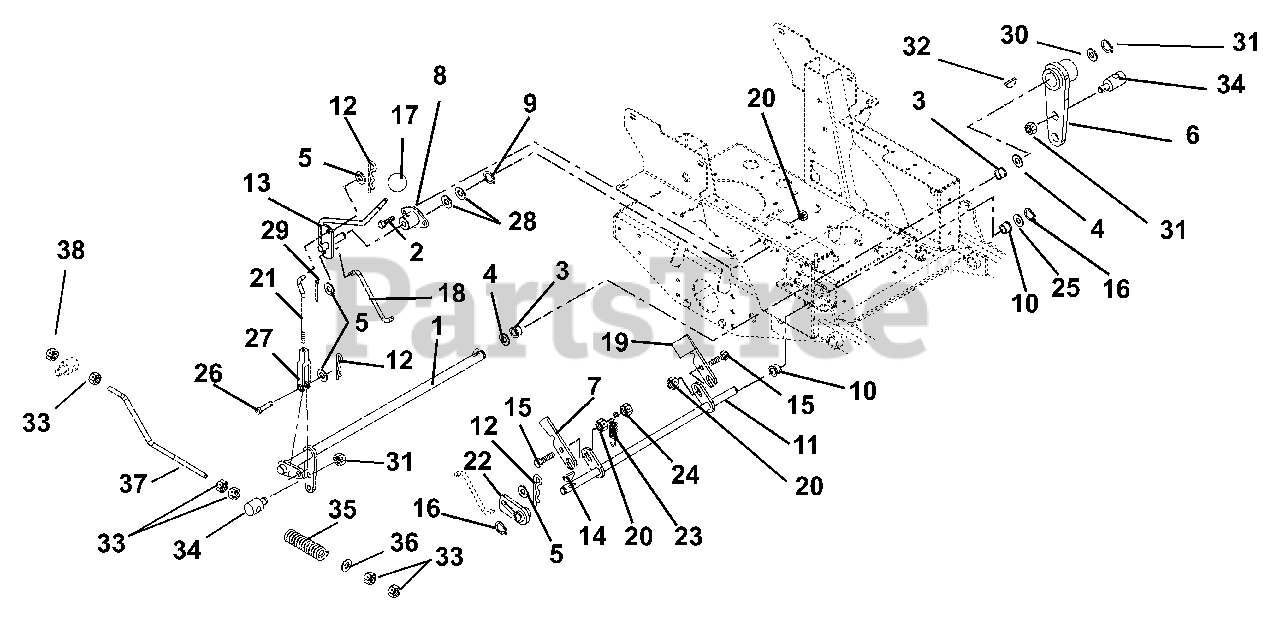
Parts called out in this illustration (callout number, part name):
1	WMT, BRAKE PIVOT
2	@BLT-HEX .31-18X1.00 GR5 YWZC
3	BSHG-FLG .762X1.0X.580X1.48 NY
4	@WSHR-FL-STL.812X1.50X.135YWZC
5	@WSHR-FL-STL.406X.812X.065 YWZ
6	WMT, BRAKE ARM
7	SLIDE, INTERLOCKING BRAKE
8	BUSHING, FLANGED
9	RG-RTNG-EXT .625X.050
10	BSHG-FLG.500X.750X.750X1.000BR
11	WMT, MECHANICAL BRAKE
12	PIN-HAIR, ENDRIES #25 YWZC
13	WMT, BRAKE ACTUATING
14	KEY-WDRF .13X.63 HRD#5
15	@BLT-RDHDSQNK .31-18X1.25 G5YZ
16	RG-RTNG-EXT .500X.050 (SNAP)
17	KNOB-STEERING LOCK
18	LINKAGE, BRAKE ACTUATING
19	INTERLOCK, SAFETY SWITCH
20	@NUT-LK-NYL-FLG .31-18 YWZC
21	LINKAGE, BRAKE COMPACT-Z
22	WMT, PARKING BRAKE HUB
23	SG-TENS .061 X .50 X 3.0 WLD 4
24	@NUT-LK-CTR .31-18 YWZC
25	WSHR-FL-STL .505X1.00X.062YWZC
26	PIN-CLEV .38X1.25 YWZC
27	CLEVIS, .38-24 ADJ.
28	WSHR-FL-STL .630X1.250X.062 YZ
29	@PIN-CTR .09X.75 EXTPRSQCT YWZ
30	WSHR-FL-STL.755X1.375X.062YWZC
31	@NUT-LK-CTR-JAM .31-18 YWZC
32	KEY-WDRF .19X.75 HRD #9
33	NUT-JAM .375-24 YWZC
34	PIN, PIVOT/TRUNNION
35	SG-COMP .142 X .710 X 2.00
36	@WSHR-FL-STL.406X.812X.065 YWZ
37	LINKAGE, BRAKE CZ
38	NUT-LK-CTR .375-24 YWZC
